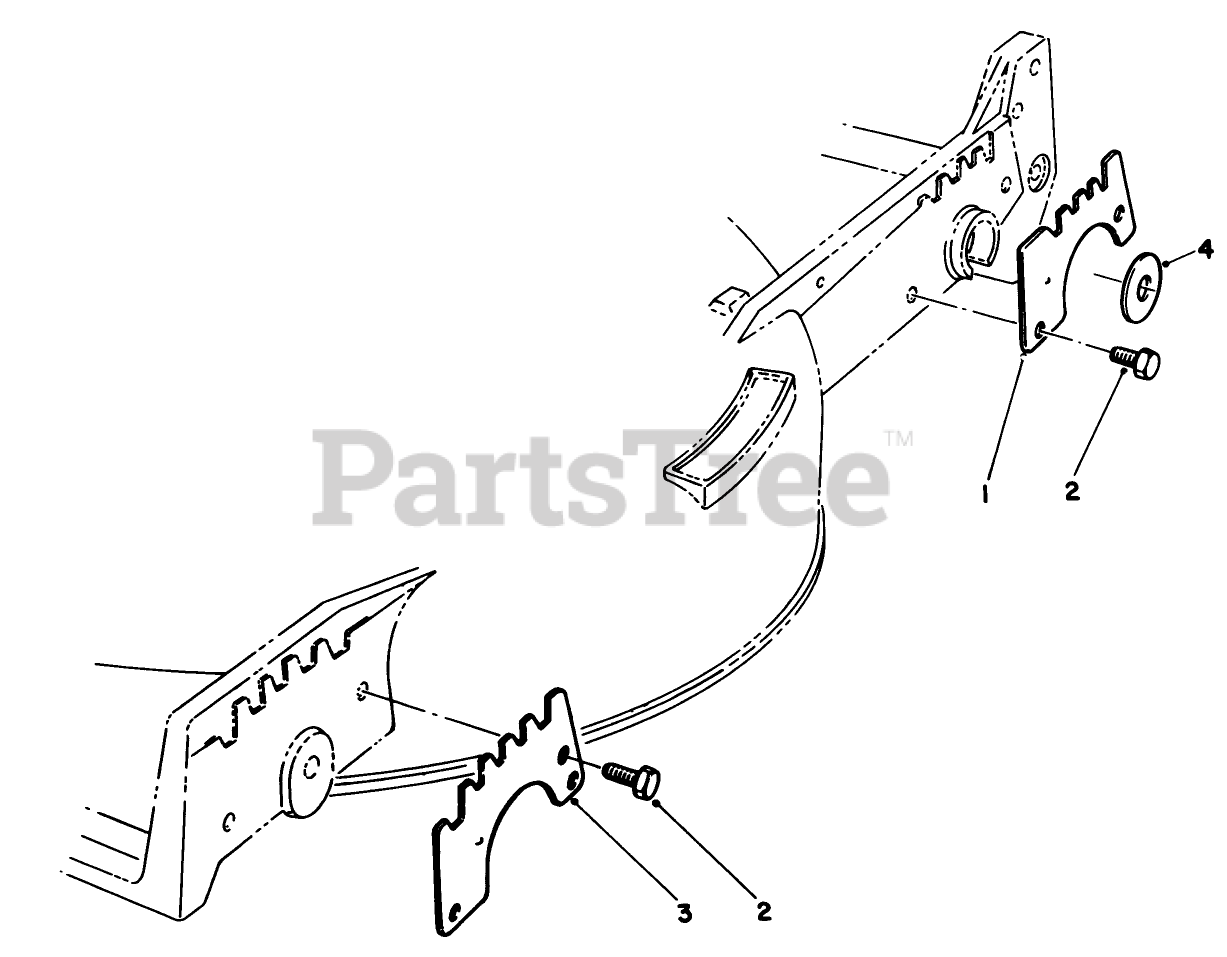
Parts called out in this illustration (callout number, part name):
1	WEAR PLATE,REAR
2	SCREW-HWH
3	WEAR PLATE
4	PIVOT WASHER
